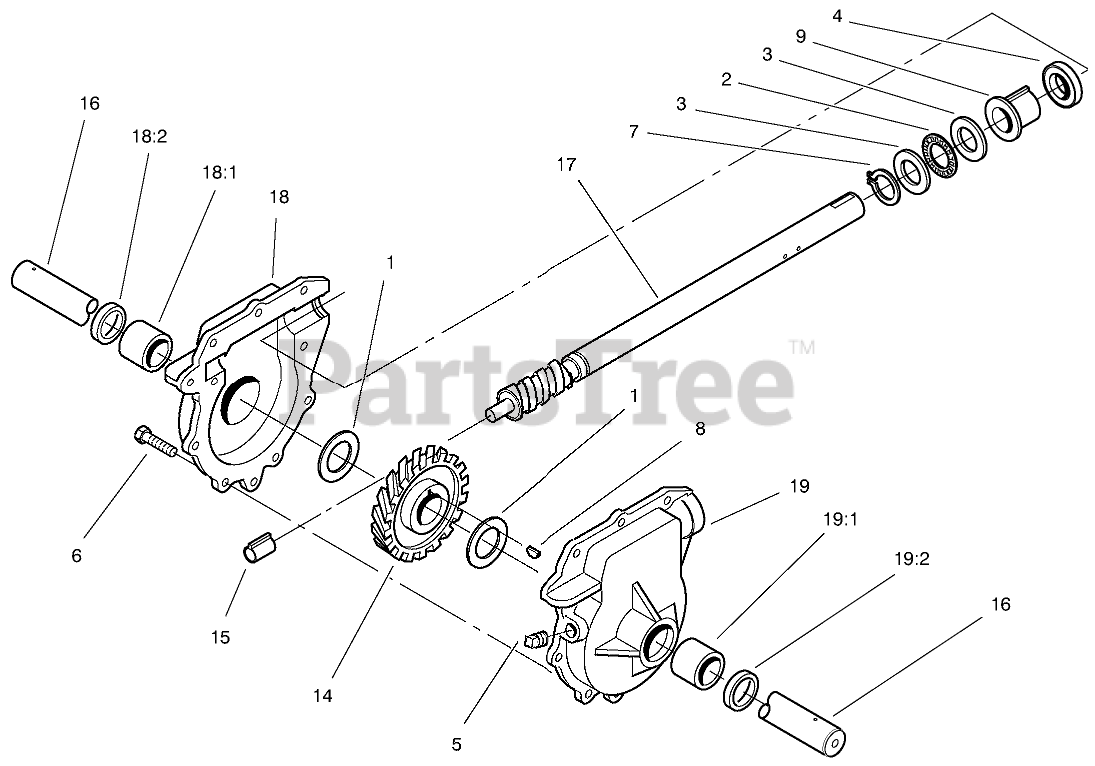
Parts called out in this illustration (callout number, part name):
1	WASHER-THRUST
2	BEARING-THRUST
3	WASHER-THRUST
4	SEAL-OIL
5	PLUG-PIPE, SQH
6	SCREW-HWH
7	RING-RETAINING, Ext
8	KEY-WOODRUFF
9	BUSHING-INPUT
14	GEAR-HELICAL
15	BUSHING-WORM
16	SHAFT-AUGER
17	Shaft-Impeller
18	ASM-Gearcase LH
18:1	BUSHING
18:2	SEAL-OIL
19	Auger Gearcase
19:1	BUSHING
19:2	SEAL-OIL
